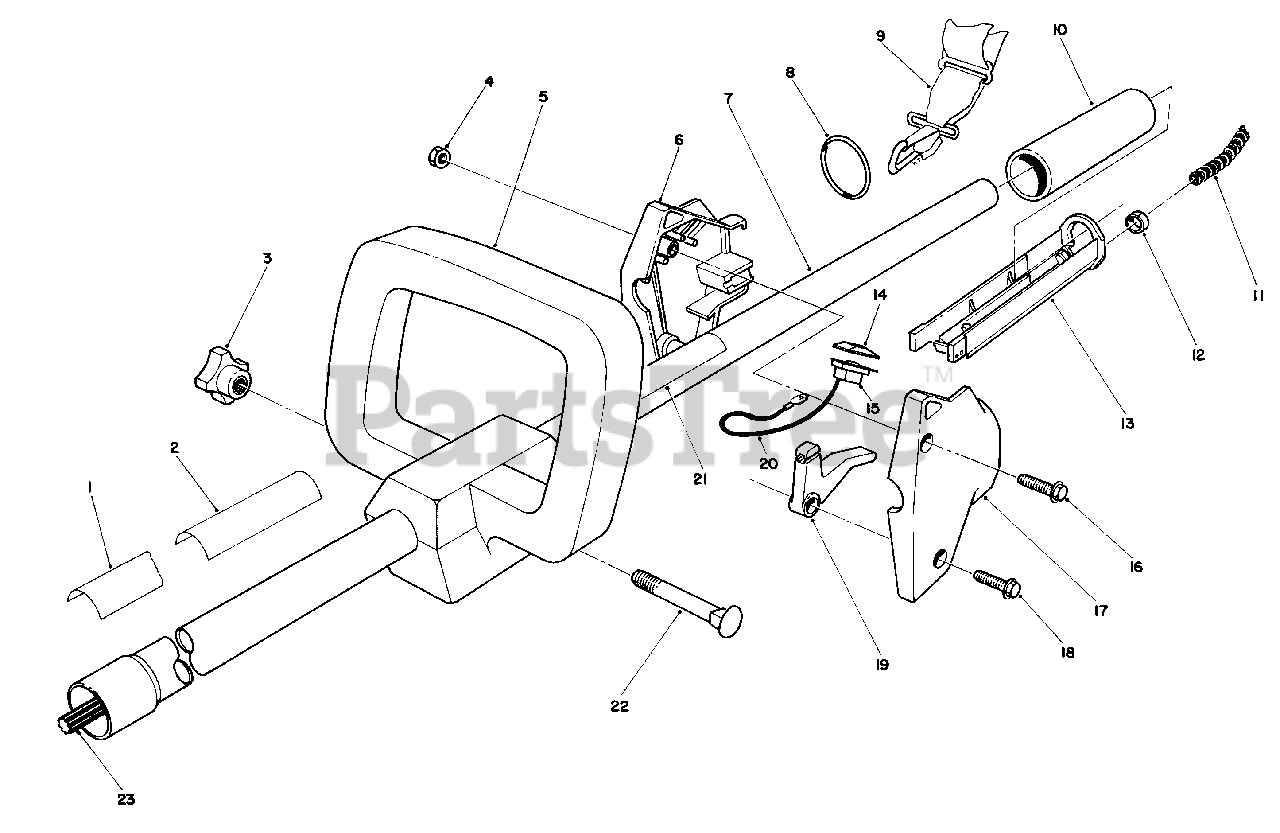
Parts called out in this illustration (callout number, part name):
1	Decal-TC 3100
2	Decal-Instruction
3	Knob-Loop Handle
6	Housing-R.H.
7	Tube Assembly
8	Ring-Harness
9	Harness-Shoulder
11	Cover-Cable
14	Cap-Switch
16	Hex Washer Hd. Screw
17	Housing-L.H.
18	Hex Washer Hd. Screw
19	Lever-Throttle
20	Wire Assembly
21	Decal-Danger
22	Carriage Bolt
23	Spline Shaft-Drive
